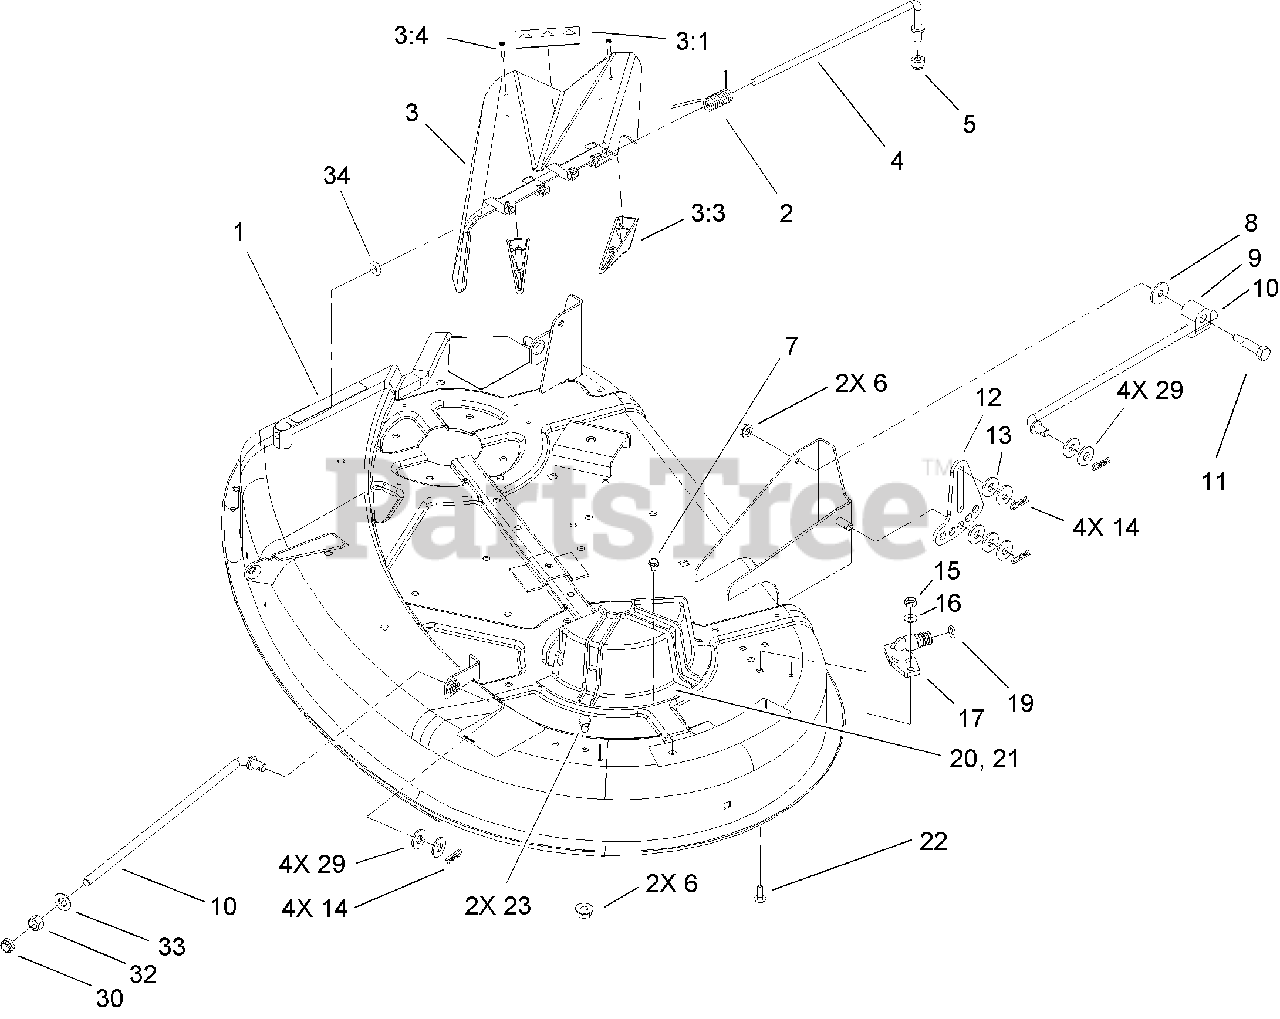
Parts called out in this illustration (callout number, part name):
1	38 IN DECK ASM
3	DEFLECTOR ASM
3:1	DECAL-DANGER
3:4	SCREW-PPH
4	ROD-PIVOT
5	NUT-LOCK, NI
8	WASHER-PIVOT
9	TRUNNION-HOC
10	ROD-HANGER
11	BOLT-SHOULDER
12	LINK-ADJUSTING, HOC
13	WASHER-HARDENED
14	PIN-HAIR
15	NUT-LOCK, NI
16	WASHER-FLAT
17	FITTING-WASHOUT
20	LH BELT GUIDE-DECK
22	SCREW-CARR
23	SCREW-HH
29	WASHER-FLAT
30	NUT-LOCK, NI
32	NUT-HEX
33	WASHER-FLAT
